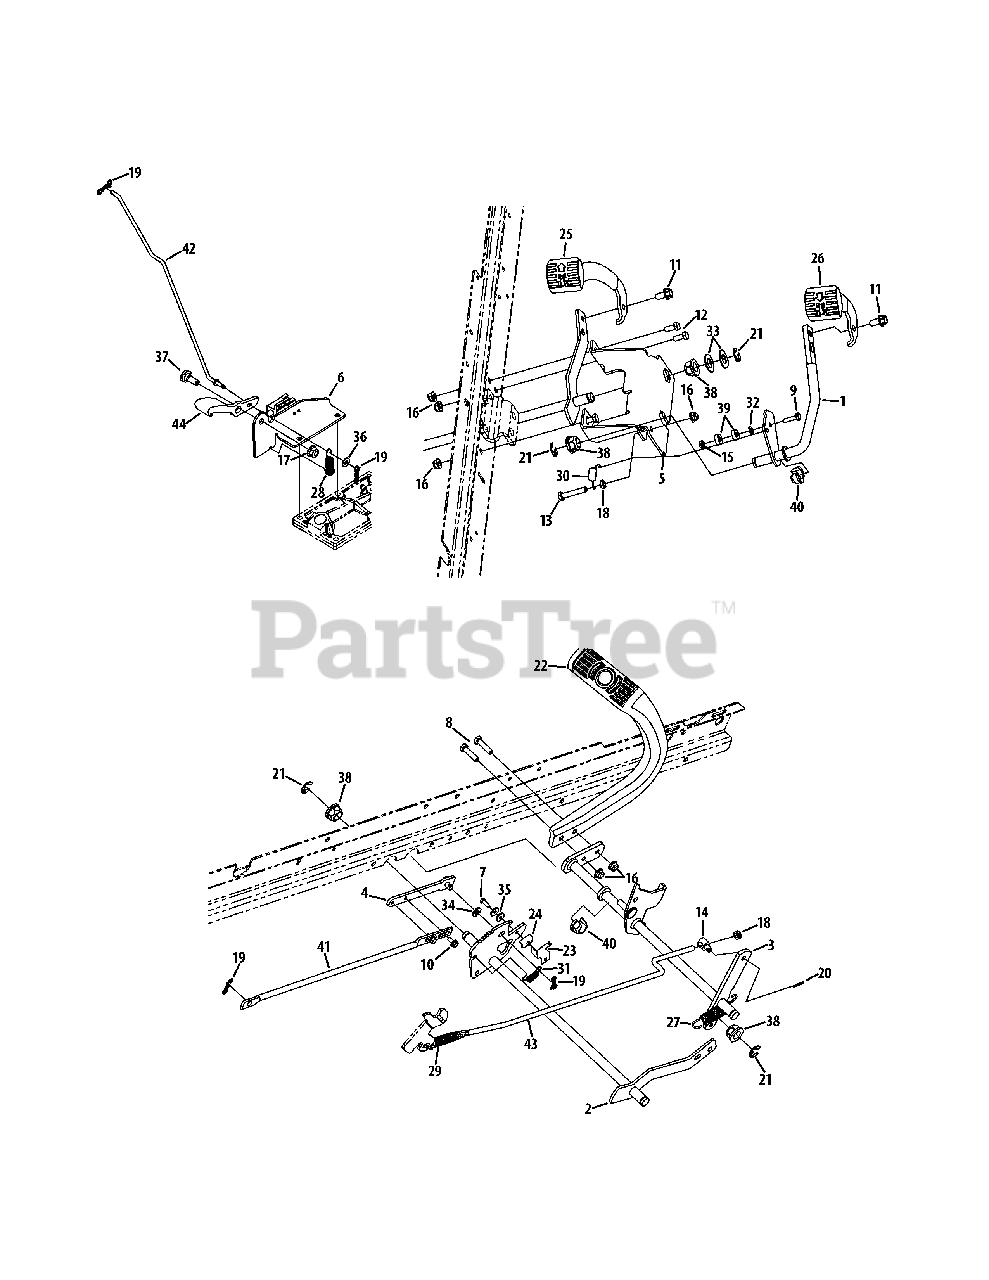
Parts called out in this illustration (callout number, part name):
1	Reverse Shaft Assembly
2	Forward Shaft Assembly
3	Brake Shaft Assembly
4	Brake Bracket Assembly
5	Pedal Bracket
6	Cruise Pedal Mount Bracket
7	Hex Screw, #10-16 x .625
8	Hex Screw, 5/16-18 x 1.25
9	Hex Screw, 1/4-20 x 1.00
10	Hex Washer Screw, 1/4-20 x .500
11	Hex Washer Screw, 3/8-16 x .750
12	Hex Screw, 5/16-18 x .75
13	Hex Screw, 5/16-18 x 1.75
14	Ferrule, 5/16-18 x .312
15	Hex Lock Nut, 1/4-20
16	Flange Lock Nut, 5/16-18
17	Flange Lock Nut, 3/8-16
18	Jam Nut, 5/16-18
19	Bow-Tie Cotter Pin, 72
20	Cotter Pin, 3/32 x .750
21	E-Ring, .625
22	Pedal Bracket
23	Single Mount Spring Switch
24	Switch Insulated Plate
25	Forward Pedal
26	Reverse Pedal
27	Extension Spring, .770 x 3.720
28	Cruise Extension Spring
29	Extension Spring, .59 x 4.00
30	Extension Spring, .51 x 2.12
31	Extension Spring, 3/8 x 1.44
32	Flat Washer, .281 x .50 x .063
33	Flat Washer, .64 x 1.24 x .06
34	Flat Washer, .344 x .688 x .065
35	Flat Washer, .194 x .62 x .063
36	Flat Washer, .271 x .630 x .065
37	Shoulder Screw, 3/8-16 x .50 x .27
38	Hex Flange Bearing
39	Ball Bearing, .25 x .6875 x .25
40	Hex Flange Bearing, .628
41	Hydro Control Rod
42	Latch Control Rod
44	Cruise Latch
